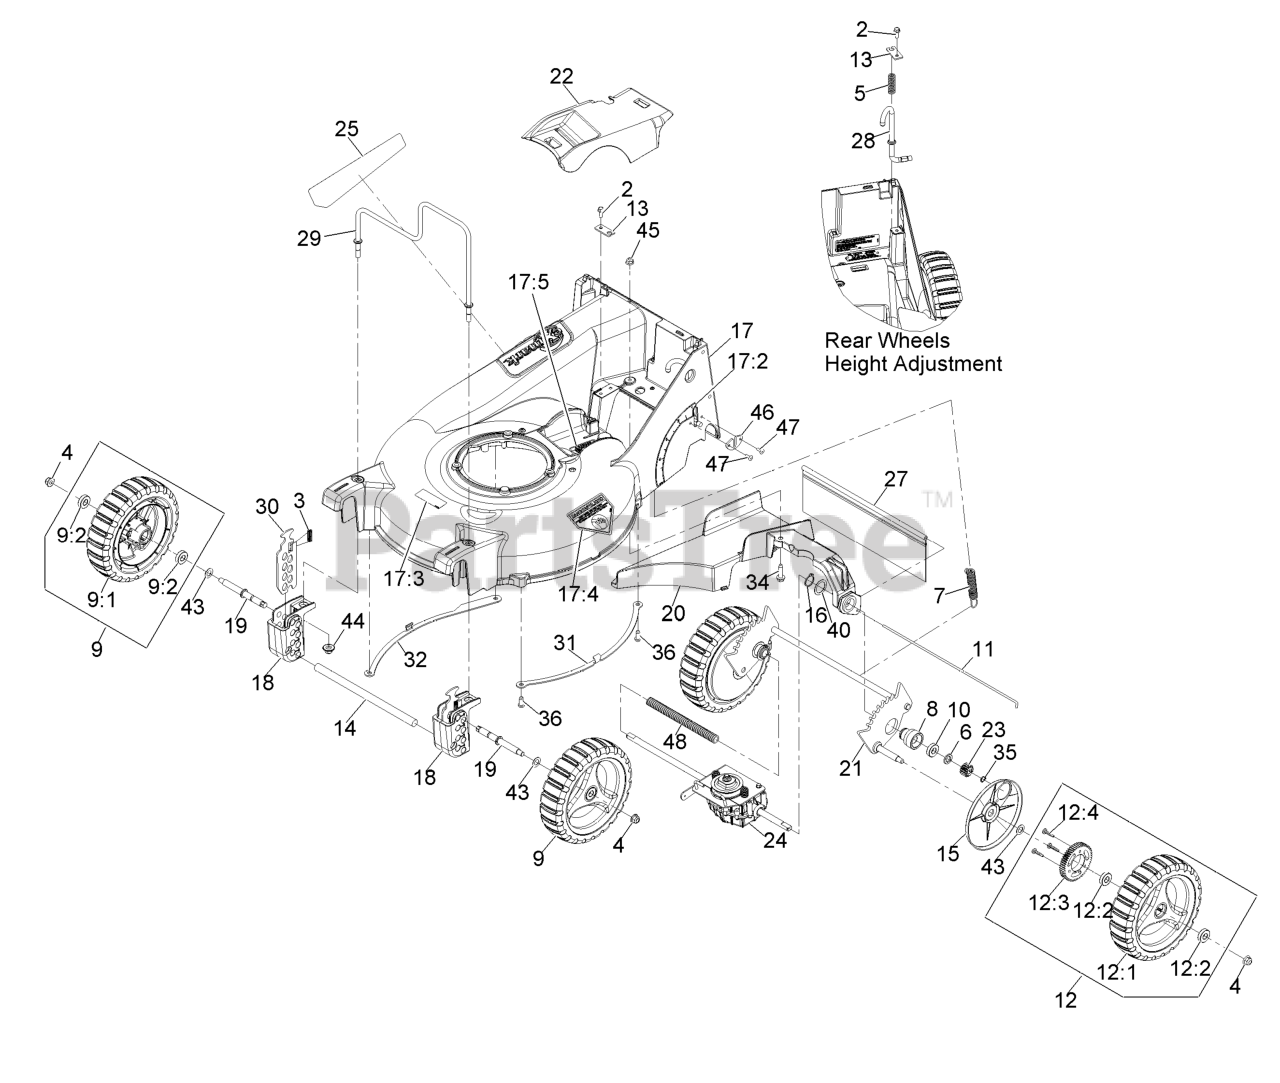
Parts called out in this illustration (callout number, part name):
2	SCREW-HWH
3	SPRING-COMPRESSION
4	NUT-HF, NI
5	SPRING-COMPRESSION
6	SPACER-BUSHING
7	SPRING-EXTENSION
9:2	BEARING-BALL
10	BEARING-BALL
11	ROD,SHIELD
12:2	BEARING-BALL
12:4	SCREW-DRIVE
13	BRACKET,MOUNT
14	ROD,BUMPER
15	COVER,GEAR
16	RING-RETAINING
17	DECK W/DECALS
17:2	DECAL-HEIGHT OF CUT
17:3	DECAL-BLADE
17:4	DECAL-DANGER
17:5	DECAL-COVER MISSING
18	BLOCK,FRONT QUADRANT
19	AXLE-WHEEL
21	WLD,REAR AXLE P21
22	COVER,BELT
24	ASM,TRANSMISSION W/BRACKE
25	DECAL-COMM 21 X-SERIES
27	SHIELD-TRAILING P21
28	ROD-HEIGHT ADJ P21
29	GUARD,ENGINE
30	PLATE, FRONT HEIGHT
34	SCREW-HWHTF
35	RING-RETAINING
36	SCREW-BHTF
43	WASHER-PLAIN
44	Nut-Nyloc 3/8-16 Flg
45	NUT-HF, NI
46	PLATE,WEAR
47	RIVET-BLIND
48	COVER-SHAFT, DRIVE
